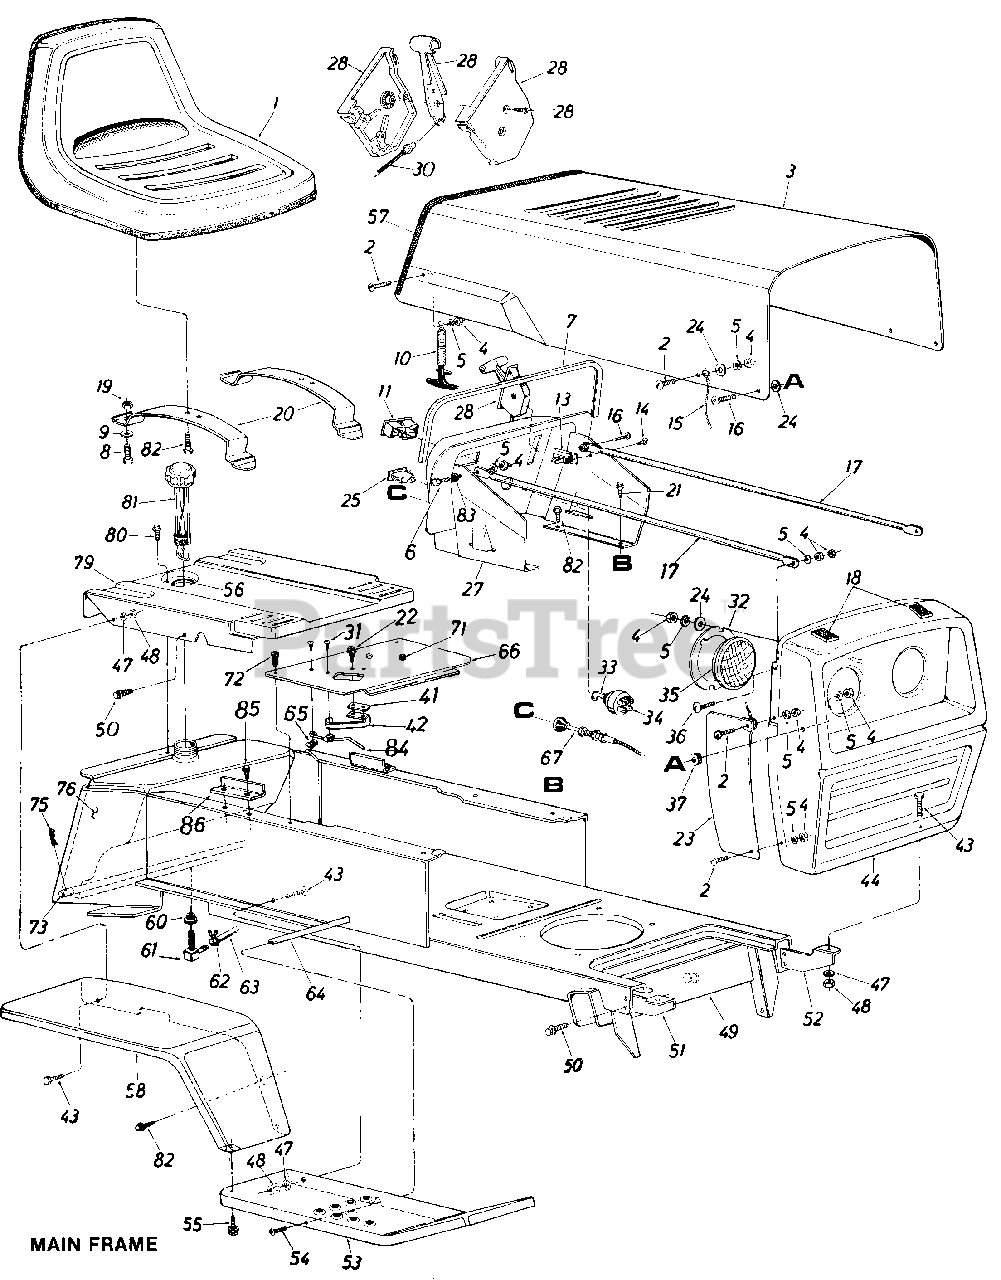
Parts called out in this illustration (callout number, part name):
1	Seat Assembly
2	Truss Mach. Scr. 1/4-20 x .50" Lg.
5	L-Wash. 1/4" Scr.
6	Truss Mach. Scr. 1/4-20 x 1.0" Lg.
7	Vinyl Molding Strip-29"
8	Hex Nylon Scr. 1/2-13 x .75" Lg.
9	Fl-Wash. .50" I.D. x 1.00" O.D. x .090
10	Hood Latch Ass'y.
11	Ammeter
13	Circuit Breaker 8 Amp.
14	Hex Tap Scr. #10 x .50" Lg.*
15	Hood Stop
16	Truss Mach. Scr. 1/4-20 x .75" Lg.
17	Grille Positioning Rod
18	PVC Foam Strip 1/2 x 1.00" x 2.00" Lg.
19	Hex Nut 1/2-13 Thd.
22	Hex AB-Tap Scr. #8 x .38" Lg.
23	Grille Side Panel-R.H.
24	Fl-Wash. 1/4" I.D.
25	Light Switch
27	Dash Panel Ass'y.
28	Throttle Control Box Comp.
30	Throttle Control Cable
31	Truss Hd. Scr. #10 x .50" Lg.
32	Head Lamp Retainer
33	Ignition Key
34	Ignition Switch
35	Head Lamp
36	Truss Machine Scr. 1/4-20 x .75" Lg.
37	Rubber Wash. .50" I.D. x 1.00 O.D. x .25 Thk.
41	Insulator Nut Plate
42	Switch Spring
43	Hex Scr. 5/16-18 x .75" Lg.
44	Grille Ass'y. (Painted)
47	L-Wash. 5/16" Scr.
48	Hex Nut 5/16-18 Thd.
49	Lower Frame Ass'y.
50	Hex Thd. Rolling Scr. 5/16" x.75" Lg.
51	Grille Mount Brkt.-R.H.
52	Grille Mount Brkt.-L.H.
53	Running Board-R.H.
54	Truss Mach. Scr. 5/16-18 x .75" Lg.
55	Hex Thd. Rolling Scr. 5/16-24 x .75" Lg.
56	Grommet
57	Vinyl Moulding Strip-30"
58	Fender Ass'y.-R.H.
60	Bushing
61	90ø Nipple
62	Hose Clamp 3/8"
63	Gas Line 46" Lg.
64	Running Board Rod
65	Speed Nut #10-24 U-Type
66	Transmission Cover
67	Choke Control Comp.
71	Snap Bushing
72	Truss Hd. Scr. #10 x .50" Lg .
73	Hitch Rod
75	Internal Cotter Pin
76	Gas Tank
79	Seat Plate
80	Hex Thd. Rolling Scr. 5/16-24 x .75" Lg.
81	Gas Gauge
82	Hex Thd. Rolling Scr. 5/16-24 x .75" Lg.
83	External Wash. 1/4" I.D.
84	Shift Lever Spring
85	Hex Thd. Rolling Scr. 1/4" x .63" Lg.
86	Seat Spring Guide
